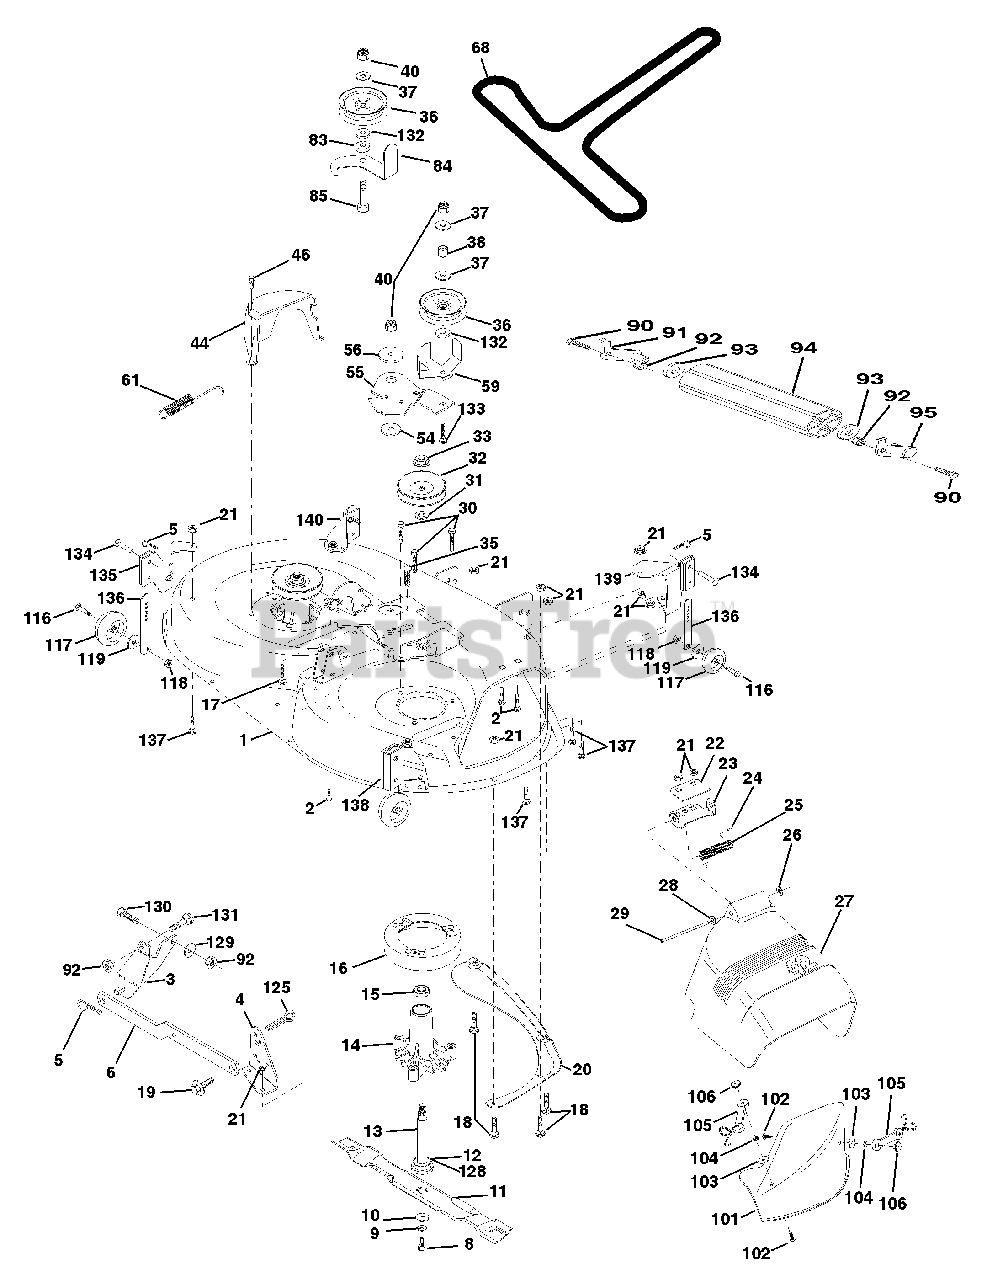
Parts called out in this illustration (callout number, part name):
1	Housing Asm Mower 42"
2	Bolt Rdhd Sqnk 5/16-18unc X3/4
3	Bracket Asm Fr Sway Bar 38/42
4	Bracket Asm Deck 42" sway Bar
5	Retainer Spring
6	Arm Suspension Rear
8	Bolt 3/8-24x1 25 Gr8 Patched
9	Washer Lock Hvy 3/8 Unplated
10	Washer Hard Blade Mower Vented
11	Blade Mower Mulching 42"
12	Bearing Ball #6204 (Mandrel)
13	Shaft Asm W/lower Bearing
14	Housing Mandrel Vented (machd)
15	Bearing Ball Mandrel
16	Stripper Round Mower
17	Bolt Rdhd Sqnk 3/8-16 X 2-1/4
18	Bolt Carr 5/16-18 X 5/8
19	Bolt Shoulder
20	Baffle Vortex 42 Heavy Duty
21	Nut Crown Lock 5/16-18
22	Stiffener Bracket 42" deck
23	Bracket Deflector Mower 42"
24	Cap Sleeve 80 x 112 Blk Mower
25	Spring Torsion Deflector 2 52
26	Nut Push Phos & Oil
27	Shield Deflector Mower 42" Blk
28	Washer 11/32 X 5/8 X 16 Ga
29	Rod Hinge 42" 6 75 Wlg
30	Screw Thdrol Washer Head
31	Washer Spacer Mower Vented
32	Pulley Mandrel 42"
33	Nut 9/16 top Lock Flng Cntr
35	Fastener Christmas Tree
36	Pulley Idler Flat 3 060
37	Washer 13/32 X 13/16 X 16 Ga
38	Spacer Spring Stop Idler
40	Nut Lock 3/8-16 Unc
44	Guard Mandrel LH Black
46	Screw Thdrol 1/4-20x5/8
54	Washer Hardened
55	Arm Idler 42" mower LT/YT
56	Spacer Retainer Pm Mower
59	Guard, Belt
61	Spring Ext. Elect
68	V-Belt Mower
83	Washer Sintered
84	Keeper Belt Idler
85	Bolt Carriage 3/8-16 x 2-1/2 Gr.5
90	Bolt Fin Hex 3/8-16unc X 1
91	Bracket Asm Noseroller LH
92	Nut Lock Hex w/ins. 3/8-16 UNC
93	Washer 17/32 X 7/8 X 16 Ga
94	Roller Nose 38 & 42
95	Bracket Asm Noseroller RH
101	Cover Mulching 42" Blk
102	Screw
103	Washer #10
104	Washer Lock #10
105	Latch Asm Bagger
106	Nut Weld .327/.304 #10-24
116	Bolt Shld
117	Wheel Gauge Donut
118	Nut Centerlock 3/8 - 16 UNC
119	Washer 3/8 x 7/8 x 14 Ga.
125	Cotter Pin
128	Washer Felt
129	Washer 13/32 x 13/16 x 12 Ga.
130	Bolt Fin Hex 3/8-16unc x 1 Gr. 5
131	Bolt Rdhd Sqnk 3/8-16 UNC
132	Washer 13/32 x 1-3/8 x 3 Ga.
133	Bolt Rd Hd 3/8-16 UNC x 2-3/4 Gr.5
134	Pin Head Rivet
135	Bracket Asm Whl Ga. Rear LH 42"
136	Bar Pnt Adjusting Wheel Gauge
137	Bolt Carriage 5/16-18 x 5/8 Short
138	Bracket Asm. Whl Ga. Rear RH 42"
139	Bracket Asm. Whl Ga. Front RH 42"
140	Bracket Asm. Whl Ga. Front LH 42"
